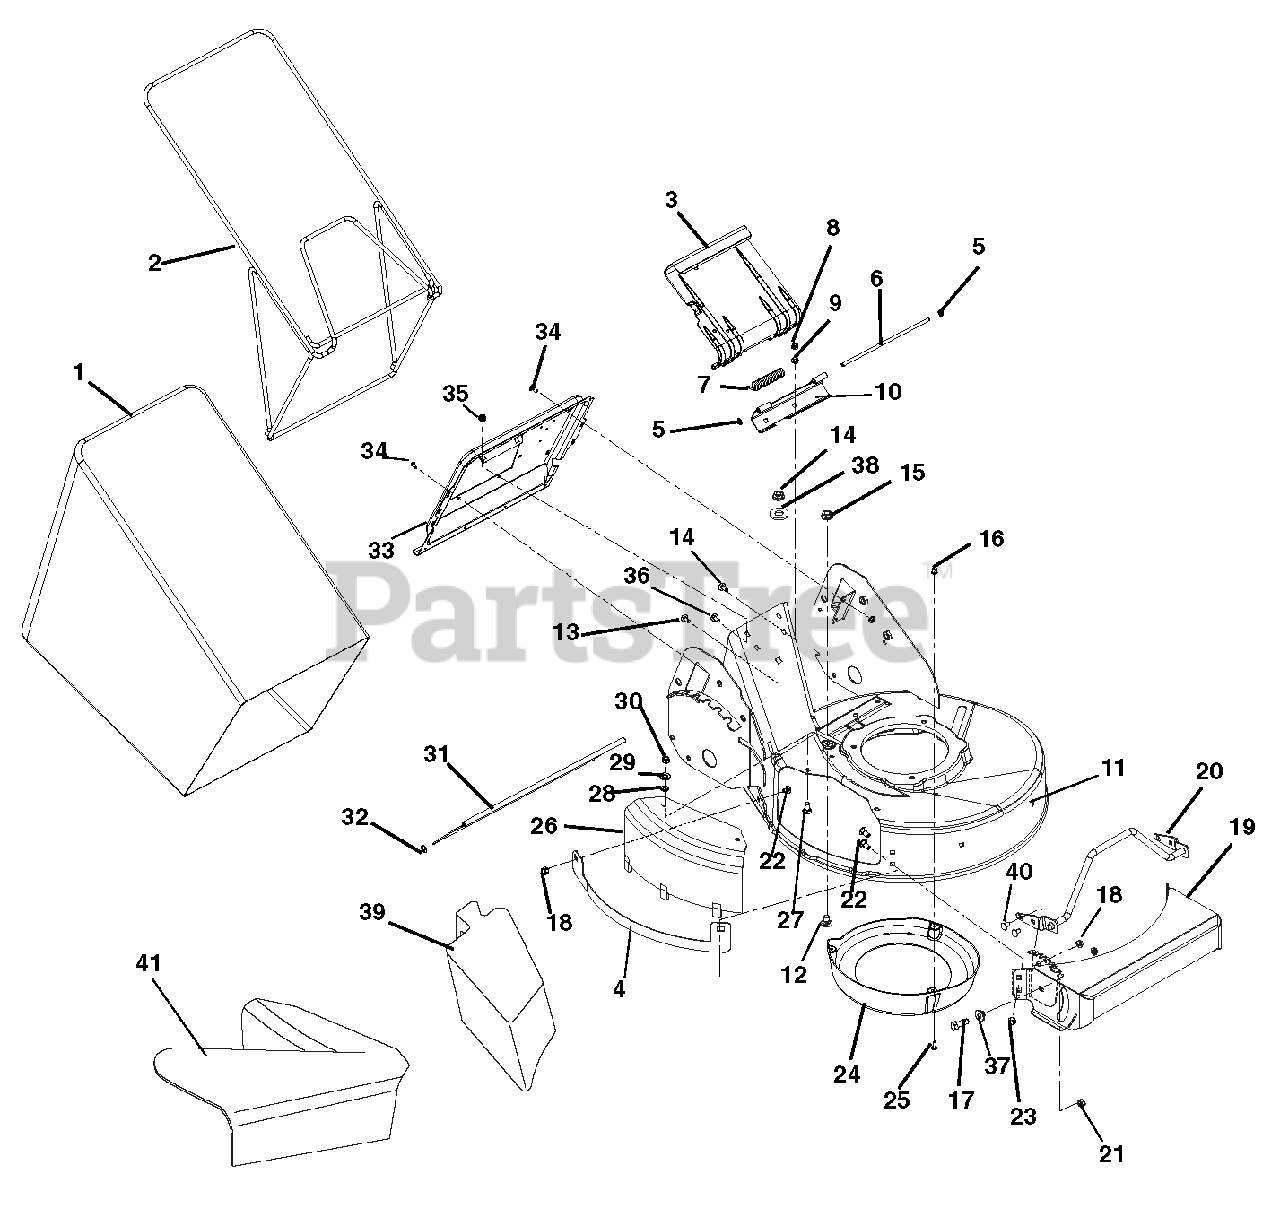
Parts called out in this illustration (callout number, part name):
1	BAG, CONSUMER BLACK 15 OZ/YD2
2	FRAME, WBLM BAGGER
3	CATCHER PLATE DOOR
4	BRKT, DISCHARGE GUARD
5	PUSH NUT, .25
6	DOOR PIN
7	SG-TORS .120X.68X3.09
8	@NUT-HEX .25-20 YWZC
9	WSHR-LK .250X.077 HVY YWZC
10	HINGE BASE
11	KIT, XD21 DECK WITH DECALS
12	@BLT-HEX .25-20X.50 GR5 YWZC
13	@BLT-HEX .38-16X.50 GR5 YWZC
14	@BLT-RDHDSQNK .25-20X.75 G5YZ
15	@NUT-SPNLK-FLG .25-20 YWZC
16	PLASTIC GROMMET
17	@BLT-HEX .31-18X1.00 GR5 YWZC
18	@NUT-LK-TOP-FLG .31-18 YWZC
19	WLDMT, COMMERCIAL 21 BUMPER
20	WLDMT, VALVE COVER GUARD
21	@NUT-LK-CTR .31-18 YWZC
22	@BLT-RDHDSQNK .31-18X.75 G5YZ
23	@NUT-SPNLK-FLG .312-18 YWZC
24	CENTER BAFFLE
25	SCR-TAP 10-16X.62 SLPH AB YWZC
26	COVER, SIDE DISCHARGE
27	BLT-RDHDSQSHK.31-18X.75 GR2 YW
28	NUT-PUSH .312
29	@WSHR-FL-STL.406X.812X.065 YWZ
30	@NUT-LK-NYL .312-18 YWZC
31	TRAILING SHIELD
32	RETAINER, .38 PUSH-ON
33	CATCHER PLATE
34	SCR-TAP 1/4-20X3/4 LPAN TL BZ
35	@NUT-SPNLK-FLG .25-20 YWZC
36	@BLT-RDHDSQNK .25-20X.50 G5YZ
37	BSHG-FLG .32X.500X.344X.880
38	WSHR-FL-STL.511X1.441X.125 YWZ
39	MULCH MASTER MULCHER ACCESSORY
40	@BLT-RHDSSQNK .31-18X.62 G5YZ
41	SIDE DISCHARGE ASSEMBLY
